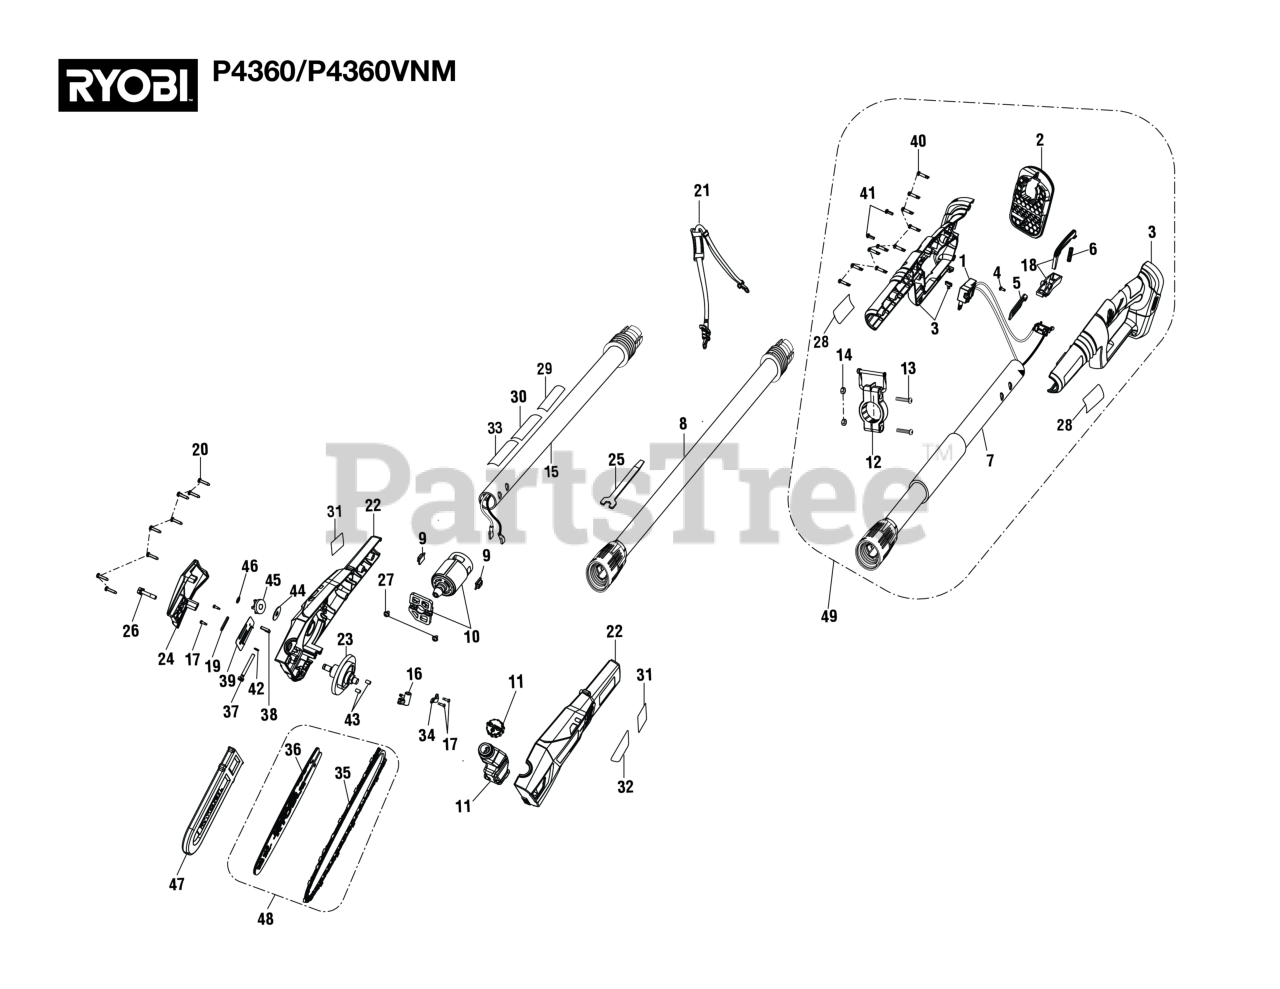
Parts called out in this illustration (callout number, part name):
1	Switch Assembly
2	18v Battery Foot
3	Handle Assembly
4	Screw (M3 x 8 mm)
5	Strap Hanger
6	Compression Spring
7	Lower Pole Assembly
8	Middle Pole Assembly
9	Rubber Bumper
10	Motor Assembly
11	Oil Tank And Cap Assembly
12	Clamp Assembly
13	Screw (M5 x 24 mm, Pan Hd.)
14	Nut (M5-0.8 x 5)
15	Top Pole Assembly
15	Top Pole Assembly w/Labels
17	Screw (M3 x 10 mm)
18	Rear Trigger & Lock Button Assembly
19	Oil Outlet Seal Ring
20	Screw (M4 x 18 mm, T20 Torx Pan Hd.)
21	Harness Assembly
22	Housing Assembly
23	Output Shaft Assembly
24	Chain Cover
26	Bolt w/Washer (M6 x 29 mm, Hex Soc. Hd.)
27	Screw w/Washer (M4 x 8 mm)
28	40V Lithium Label (Right)
29	Warning Label (English)
30	Warning Label (French/Spanish)
31	Logo Label
32	Data Label
33	Warning Icon Label
34	Pump Clamp
36	Guide Bar
37	Adjustment Bolt (M5 x 46.5 mm)
38	Adjustment Guide Bar
39	Guide Bar Plate
40	Screw (M4 x 18 mm, T20 Torx Pan Hd.)
41	Screw (M4 x 11 mm, T20 Torx Pan Hd.)
42	Retaining Ring (4 mm)
43	Contact Plate Stopper
44	Cover Plate (Internal "D" Washer)
46	Retaining Ring
48	Bar & Chain Assembly
49	Rear Handle Assembly
